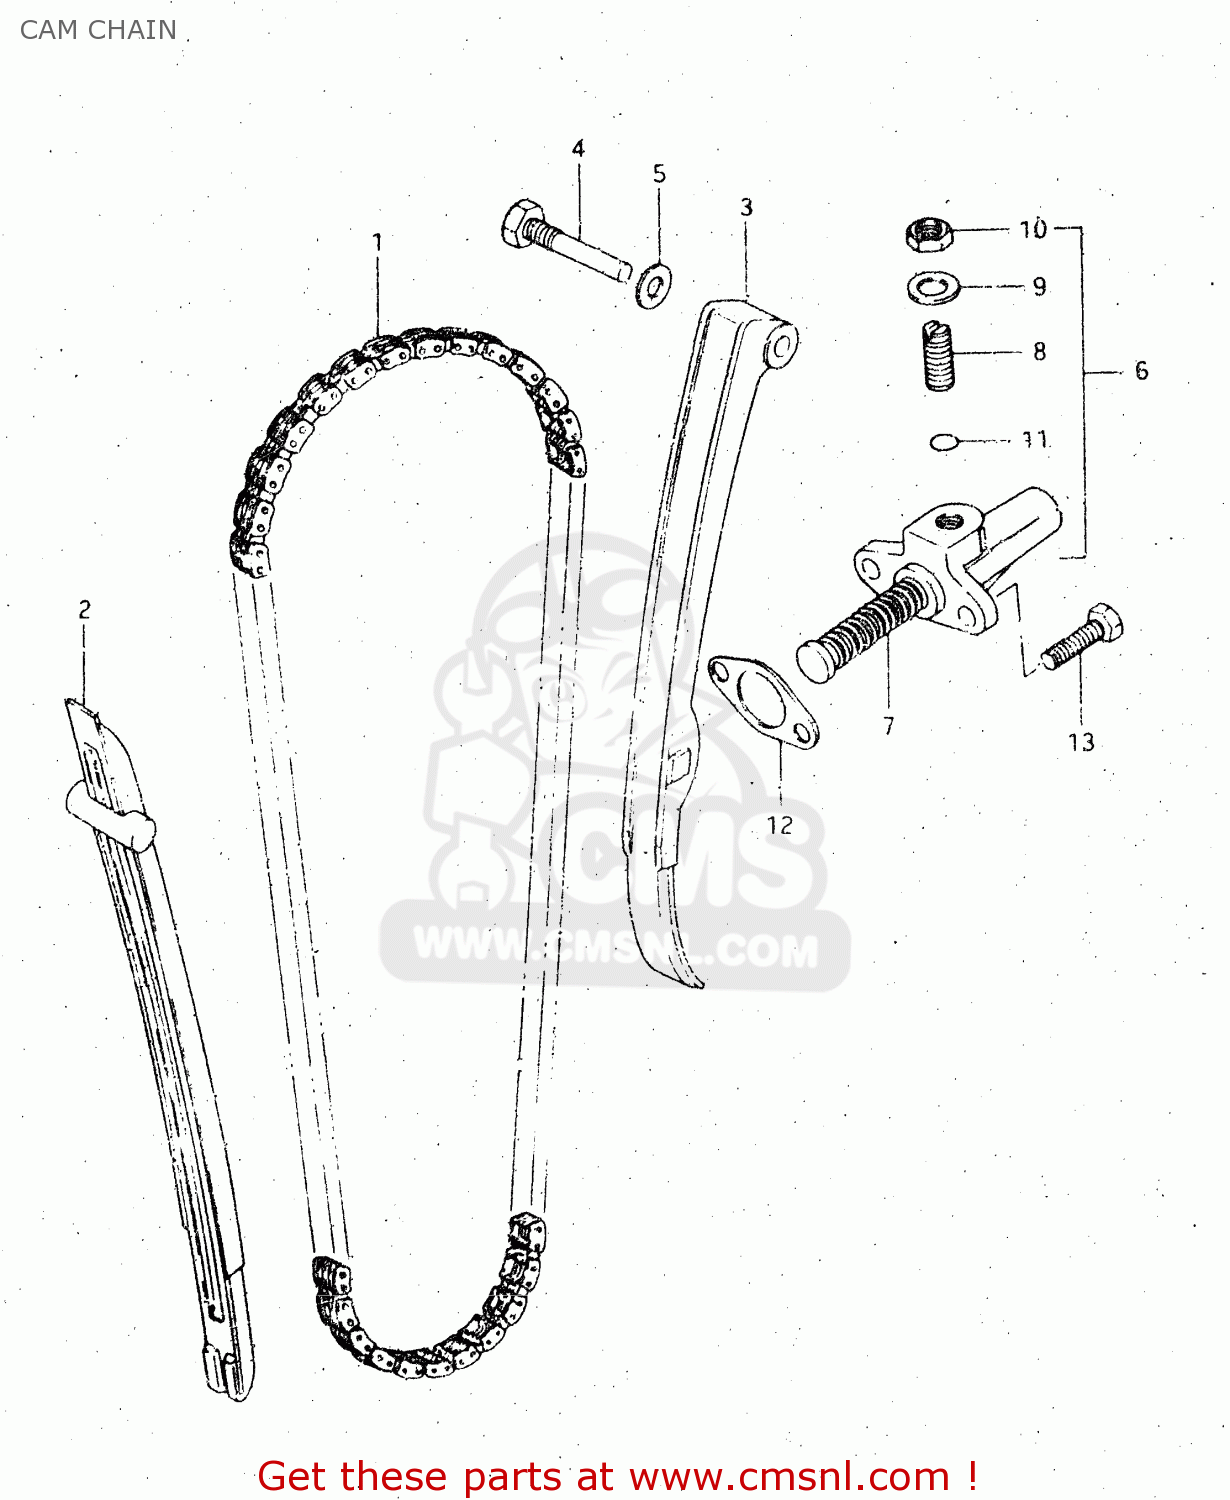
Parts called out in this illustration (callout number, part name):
1	CHAIN,CAMSHAFT DRIVE
2	GUIDE,CAM CHAIN
3	TENSIONER,CAM CHAIN
4	BOLT,CAM CHAIN TENSIONER
5	GASKET 8.2X14X1 (NAS)
6	ADJUSTER ASSEMBLY,TENSIONER
7	SPRING
8	SCREW
9	WASHER,8.5X16X
10	NUT
11	O RING(D:1.9,ID:5.7)
12	GASKET,TENSIONER ADJUSTER (NAS)
13	BOLT
